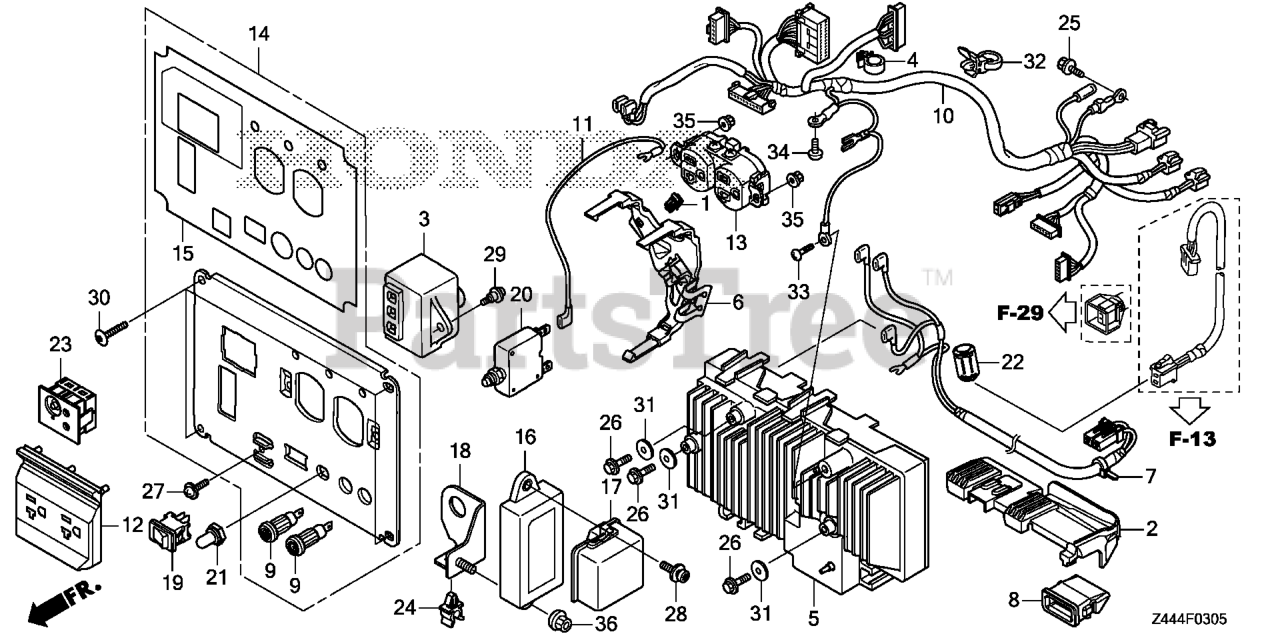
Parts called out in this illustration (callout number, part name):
1	CLIP, TUBE
2	RUBBER B, TANK MOUNTING
3	SPARK UNIT
4	CLIP, HARNESS
5	INVERTER UNIT
6	BRACKET, INVERTER HARNESS
7	SUB-WIRE HARNESS ASSY.
8	COVER, CONNECTOR
9	SOCKET, COMPOSITE
10	WIRE HARNESS ASSY., CONTROL
11	WIRE, TERMINAL
12	COVER, RECEPTACLE (20A-125V)
13	RECEPTACLE ASSY. (125V-20A) (MATSUSHITA)
14	PANEL, CONTROL
15	MARK, CONTROL PANEL
16	SENSING UNIT (CO)
17	COVER, SENSING UNIT PROOF (CO)
18	BRACKET, SENSOR UNIT (CO)
19	SWITCH, AUTO-THROTTLE (OTAX)
20	PROTECTOR, CIRCUIT (20A) (WHITE)(TYCO)
20	PROTECTOR, CIRCUIT (20A) (BLACK)(JOEMEX)
21	COVER, CIRCUIT PROTECTOR
22	FILTER, SUB NOISE (AC)
23	LED ASSY., INDICATER
24	CLIP, TUBE
25	BOLT, FLANGE (5X10)
26	BOLT, FLANGE (5X12)
27	SCREW, PAN (5X12) (GROUND CABLE)
28	BOLT-WASHER (5X15) (TORX)
29	SCREW, PAN (5X13)
30	SCREW, TAPPING (5X16) (TORX)
31	WASHER, PLAIN (20MM)
32	BAND (100MM) (BLACK)
33	SCREW, PAN (5X8)
34	SCREW, PAN (5X10)
35	NUT, FLANGE (4MM)
36	NUT, FLANGE (5MM)
